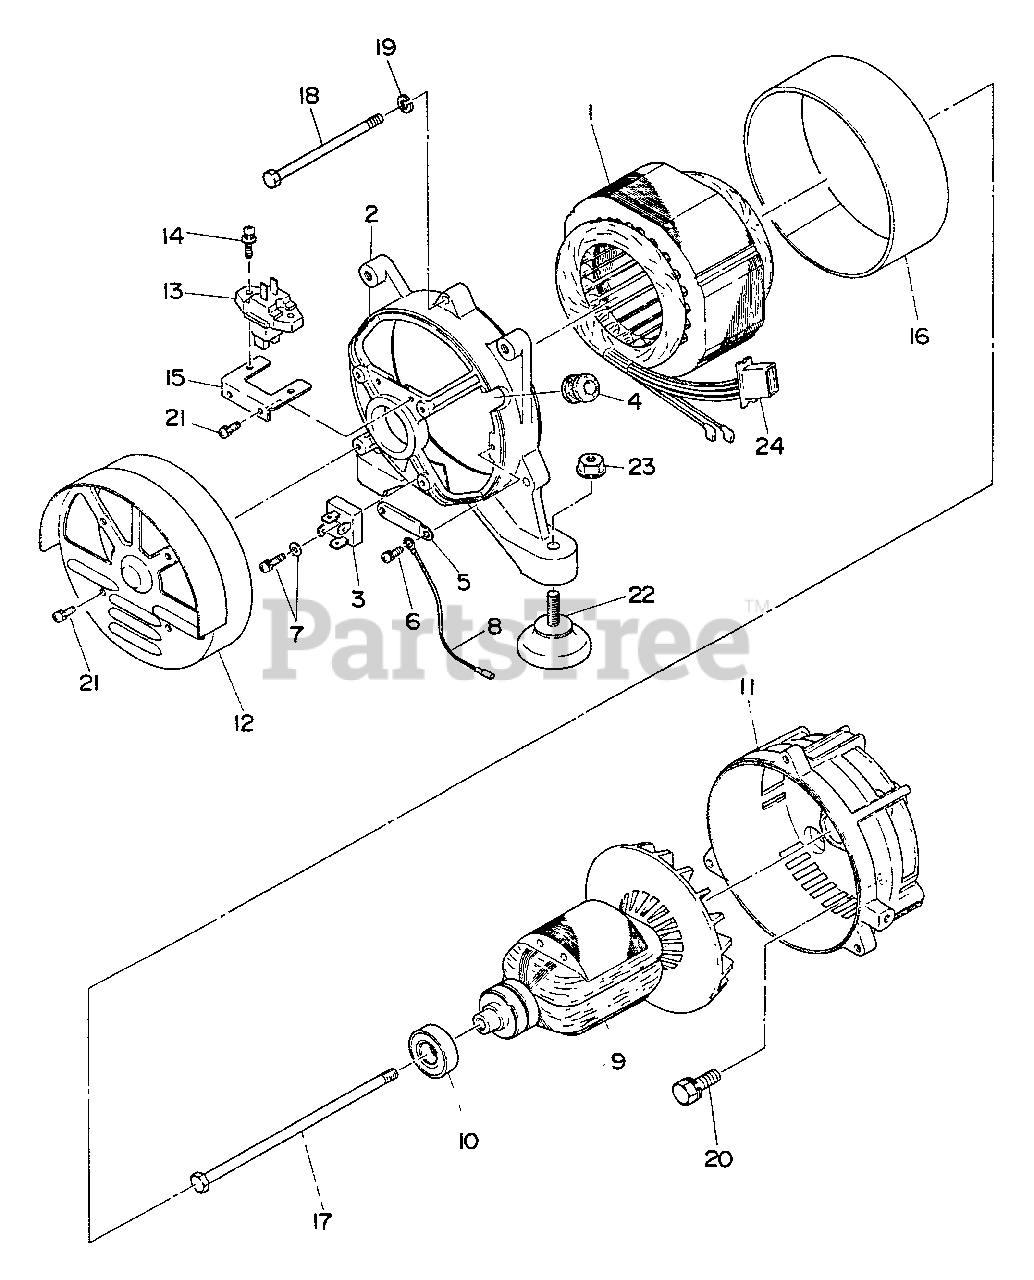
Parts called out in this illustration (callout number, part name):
1	STATOR ASSY
2	BRACKET - REAR
3	DIODE STACK ASSY
4	GROMMET
5	CLAMP
6	SCREW
7	SCREW
8	LEAD - GROUND
9	ROTOR ASSY
10	BEARING, BALL
11	BRACKET, FRONT
12	COVER
13	HOLDER, BRUSH
14	SCREW
15	BRUSH HOLDER BASE
16	STATOR COVER
17	BOLT
18	BOLT
19	LOCKWASHER
20	BOLT
21	SCREW
22	MOUNT ASSY
23	NUT - 8 -- FLANGE
24	LABEL - GENERATOR
